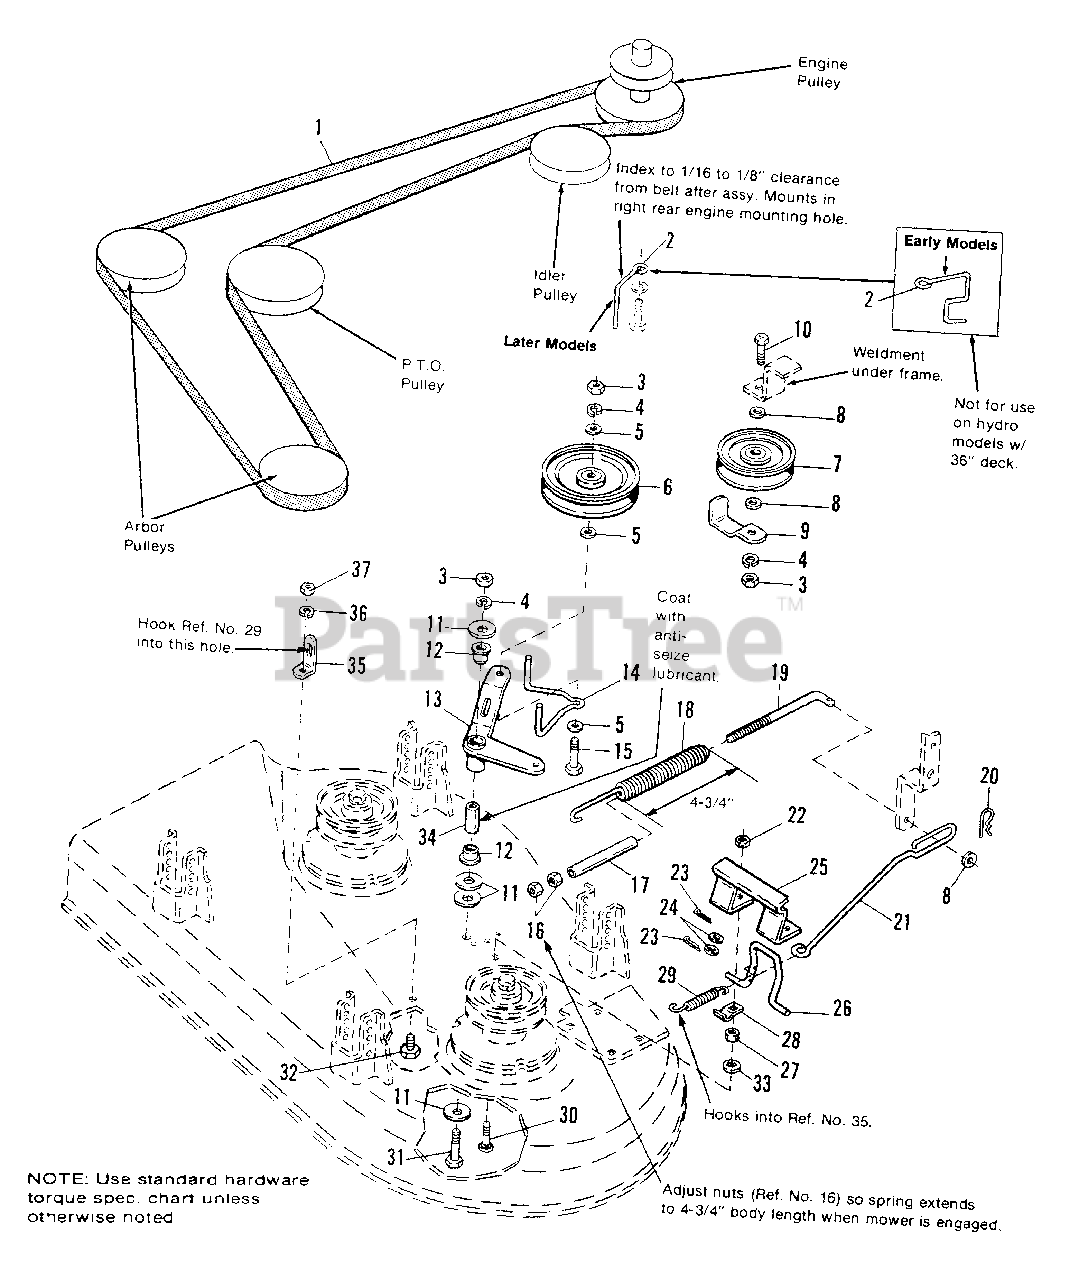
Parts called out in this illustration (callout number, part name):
1	BELT, Drive
2	GUIDE, Belt (Early Models)
2	GUIDE, Belt (Later Models)
3	NUT, Hex, 3/8-16
4	LOCKWASHER, 3/8
5	WASHER, 3/8 x 7/8
6	PULLEY, P.T.O., Mower
7	PULLEY, Idler
8	WASHER
9	GUIDE, Belt
10	CAPSCREW, 3/8-16 x 1-1/2
11	WASHER, 13/32 x 1-1/2
13	ARM ASSY., Clutch
14	STOP, Belt
15	CAPSCREW, Hex Hd., 3/8-16 x 1-3/4
16	NUT, Hex Jam, 5/16-18
20	CLIP, Hair Pin
22	NUT, Hex Centerlock Jam, 5/16-18
23	PIN, Cotter
24	WASHER, 3/8
25	BRACKET, Brake
26	ROD, Brake
30	CARRIAGE BOLT, 5/16-18 x 1-1/4
31	CAPSCREW, Hex Hd., 3/8-16 x 2-1/4
32	CAPSCREW, 1/4-20 x 3/4
33	NUT, Retainer, 5/16
36	LOCKWASHER, 1/4
37	NUT, Hex, 1/4-18
